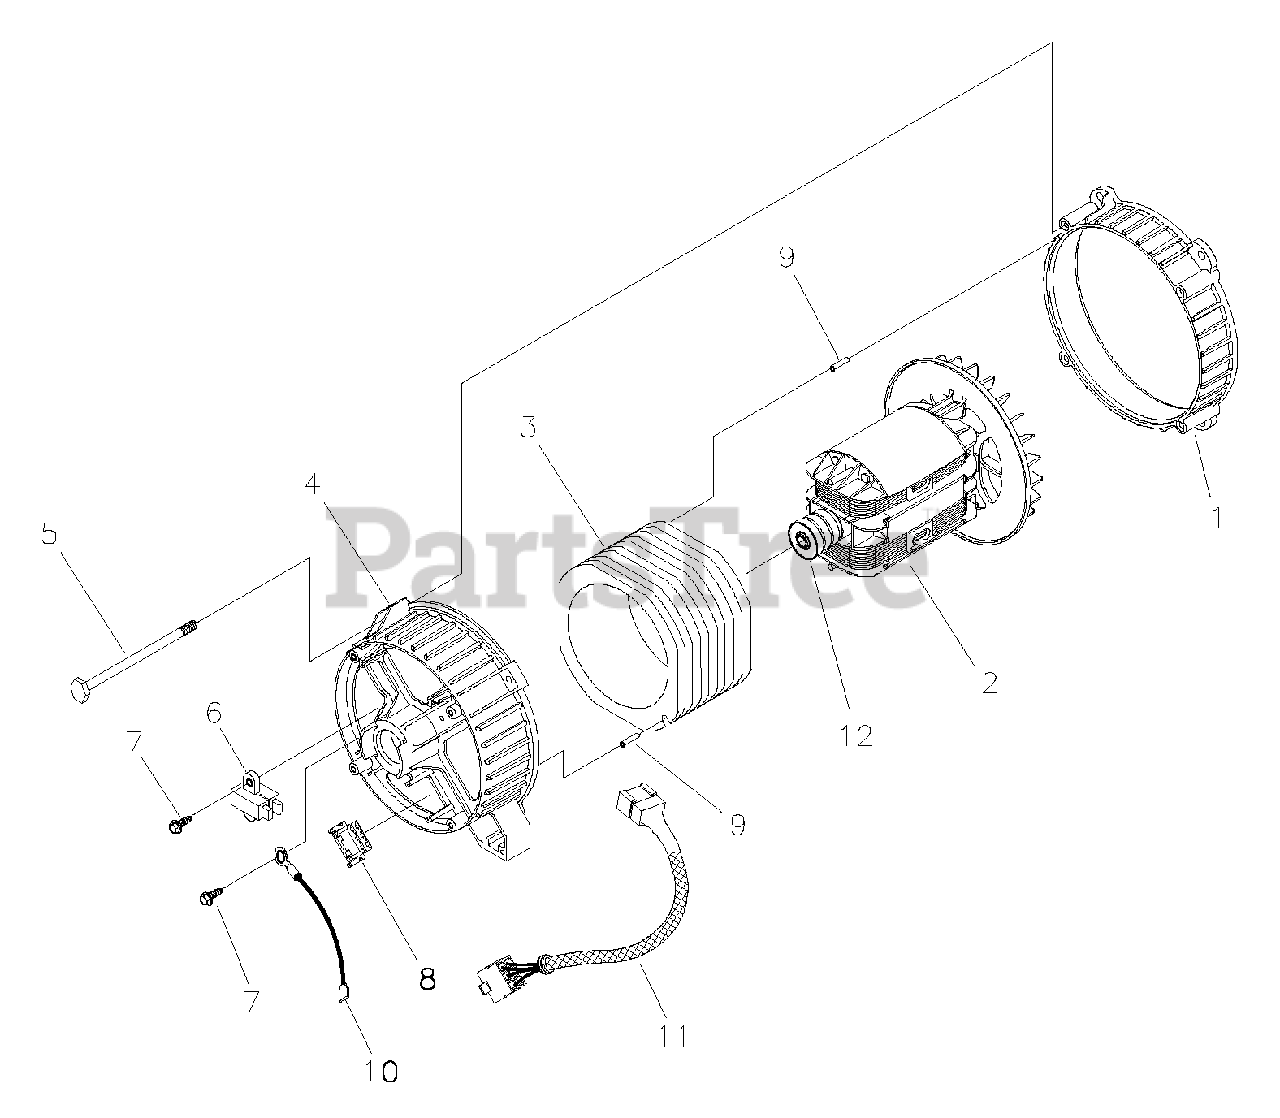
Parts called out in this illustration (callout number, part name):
1	ADAPTER, Mounting,Alternator
4	RBC, with O-Ring (p/n 189197GS)
5	HHCS, M6 - 1.0 x 130 SEMS
6	ASSY, Holder, Rectifier/Brush
7	TAPTITE, M5 - 0.8 x 16
8	RECEPTACLE, 6 pin
9	PIN, Roll, 4mm x 10
10	ASSY,Wire, Ground
11	HARNESS,Wire, Power
12	BEARING
